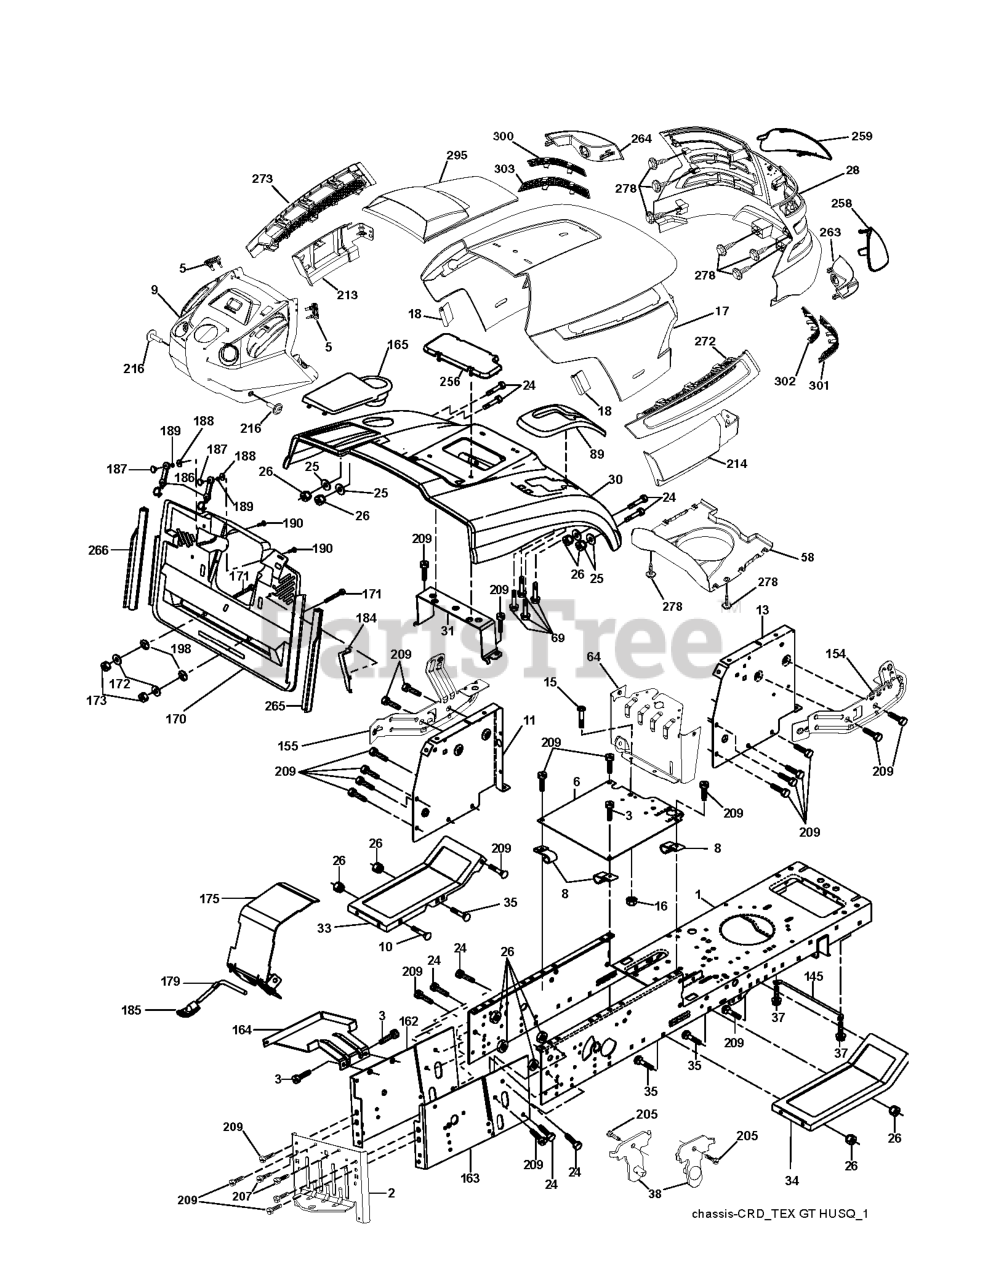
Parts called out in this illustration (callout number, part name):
2	DRAWBAR
3	SCREW 3/8-16X3/4
5	BUMPER DASH
6	PLATE
8	CLIP,INSULATOR
10	BOLT D
11	PANEL DASH LH
13	PANEL DASH RH
15	Screw, Machine, Truss Head 5/16-18 UNC x 3/4
16	NUT
17	HOOD
18	BUMPER.HOOD.TEX.HUSQVARNA
25	WASHER
26	NUT
28	GRILL.ASM.HUSQ.TG/CRD.W/TRIM
30	CONSOLE.CRD.AUTO.GRY
31	BRACKET SUPPORT FENDER
33	FOOTREST PNT LH
34	FOOTREST PNT RH
37	Screw 5/16-18 x 1/2 Hex, Self Tapping 5/16-18 x 1/2
38	BRACKET ASM PIVOT MOWER REAR
58	AIR.DUCT.HOOD.TEX.GT.HUSQ
69	SCREW.HI-LO.CONSOLE
89	CONSOLE.CRD.AUTO.GREY.2005
145	ROD.PIVOT.HOOD
162	BRACKET
163	BRACKET EXTEN CHASSIS RH CRD
165	RP.COVER.BATTERY.CRD.GREY
172	WASHER
175	DOOR TRAP
179	ROD PIVOT FBI
184	BRACKET.ACTUATOR.BAGGER.SRD
186	LATCH ASSY
187	WELDNUT
189	LOCKWASHER #10
190	SCREW
207	SCREW, 5/16-18 X 1/2
209	SCREW, 3/8-16X3/4
213	SKIRT.HOOD.SIDE.HUSQ.LH.GREY
214	SKIRT.HOOD.SIDE.HUSQ.RH.GREY
216	SCREW 14-20 X 5/8
256	COVER FENDER CRD
258	LENS.RH.TEX.GT.HUSQ.CL
259	LENS.LH.TEX.GT.HUSQ.CL
263	BEZEL.RH.TEX.GT.HUSQ
264	BEZEL.LH.TEX.GT.HUSQ
265	SEALING
266	SEALING
272	VENT.SIDE.HOOD.HUSQ.RH.GREY
273	VENT.SIDE.HOOD.HUSQ.LH.GRAY
278	SCREW
295	VENT.ASM.TORPHD.HUSQGT.LOGO.CL
300	INSERT.HEX.GRILL.HUSQ.
301	INSERT.HEX.GRILL.HUSQ.GREY
302	INSERT.HEX.GRILL.HUSQ.
303	INSERT.HEX.GRILL.HUSQ.
